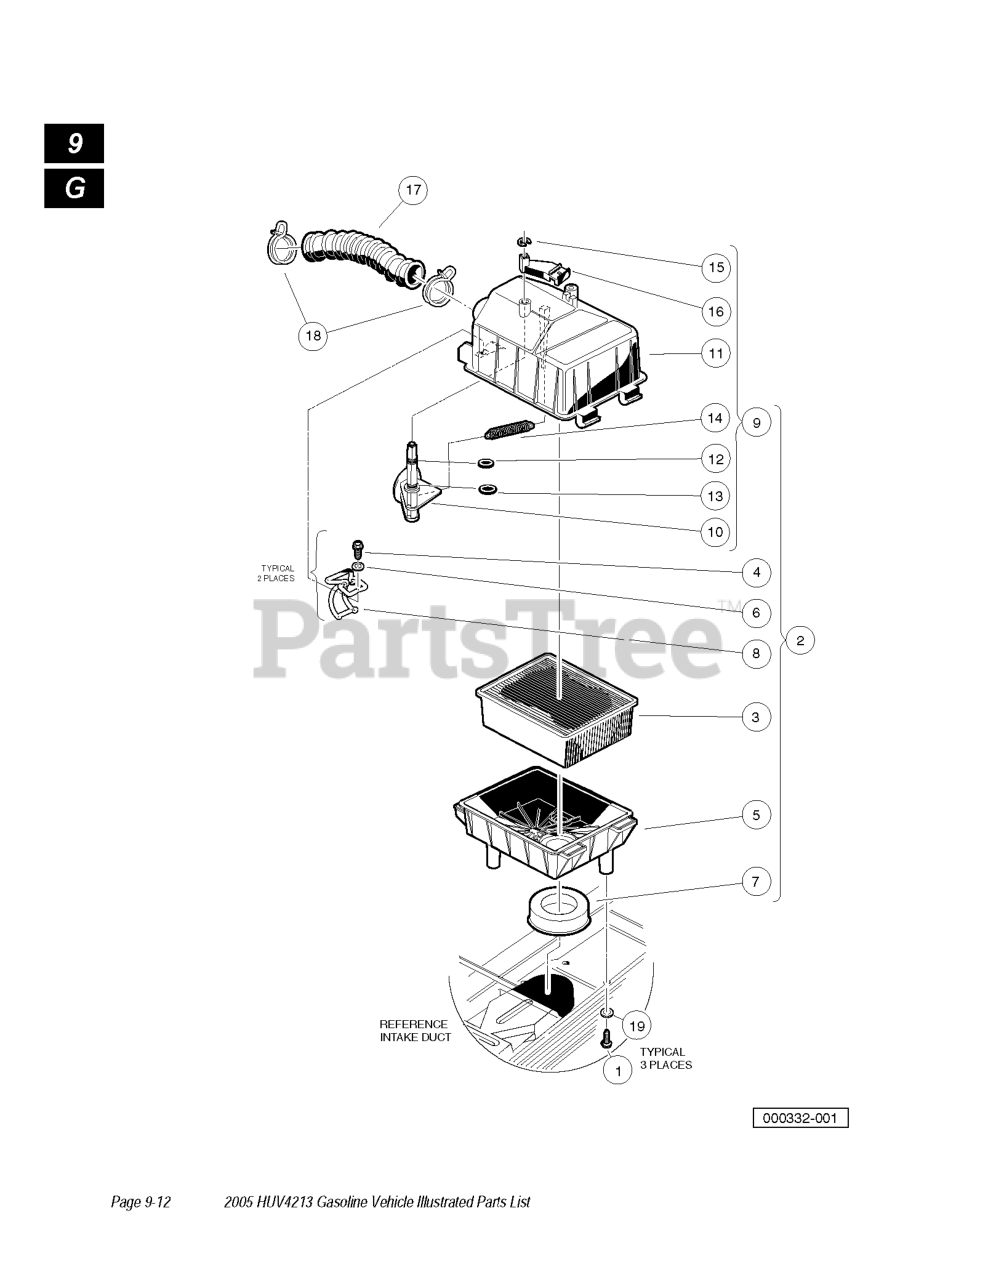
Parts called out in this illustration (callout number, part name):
1	SCREW, #12-16 X .625 HI-LO
2	AIR BOX ASSY
3	AIR FILTER OHV
4	SCREW, #8 X .500 HX HD HI-LO
5	BOTTOM, AIR BOX
6	WASHER, #8 SS FLAT WASHER
7	SEAL, INTAKE
8	LATCH, WIREFORM
9	TOP ASSY, AIR BOX
14	SPRING, EXTENSION RETURN
15	RETAINING RING .25 SHAFT
16	LEVER, CHOKE
17	AIR INTAKE HOSE
18	CLAMP, 1.58" ID HOSE
19	WASHER 1/4 FLAT
